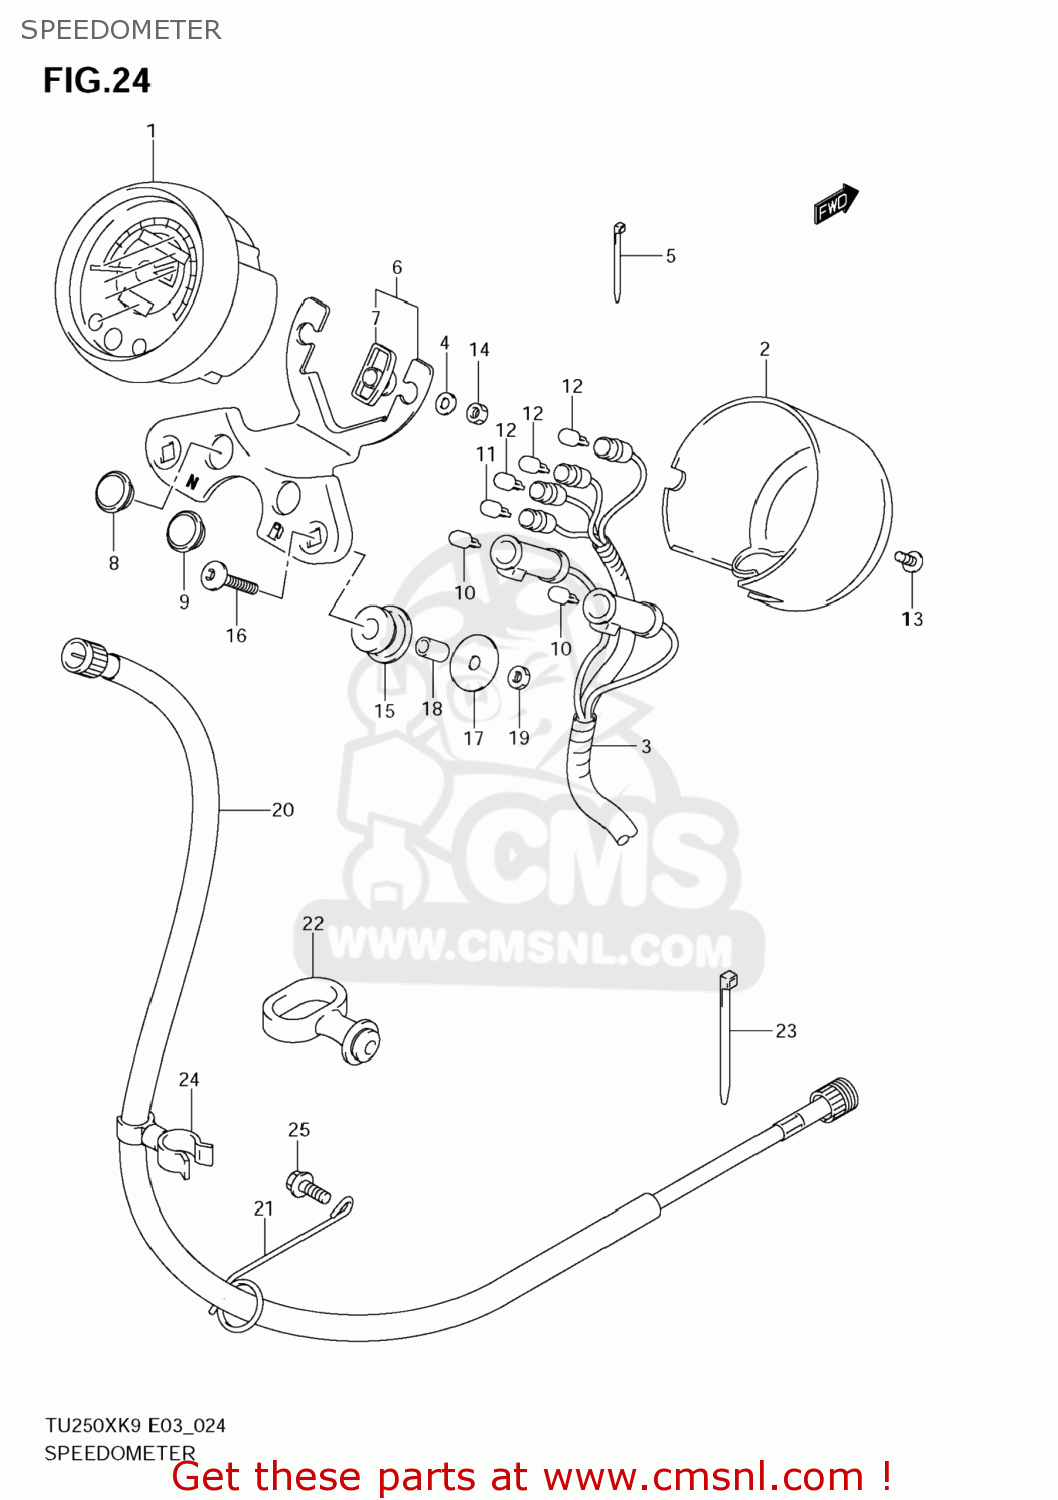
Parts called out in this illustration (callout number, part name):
1	SPEEDOMETER
2	COVER,UNDER(CHROMUN)
3	CORD ASSY
4	WASHER
5	RIEM
6	BRACKET ASSY
7	CUSHION,DAMPER
8	LENS(GREEN)
9	LENS(ORANGE)
10	BULB(12V3.4W,T10)
11	BULB(12V3W,T6.5)
12	BULB(12V1.7W,T6.5)
13	SCREW,METER
14	NUT
15	CUSHION,METER BRACKET
16	BOLT(6X30)
17	WASHER(6.5X28X1.6)
18	SPACER(6.5X10X15.7)
19	NUT
20	CABLE ASSY,SPEEDOMETER
21	GUIDE,SPEEDOMETER CABLE
22	GUIDE,CABLE
23	CLAMP(L:145)
24	CLAMP
25	BOLT
